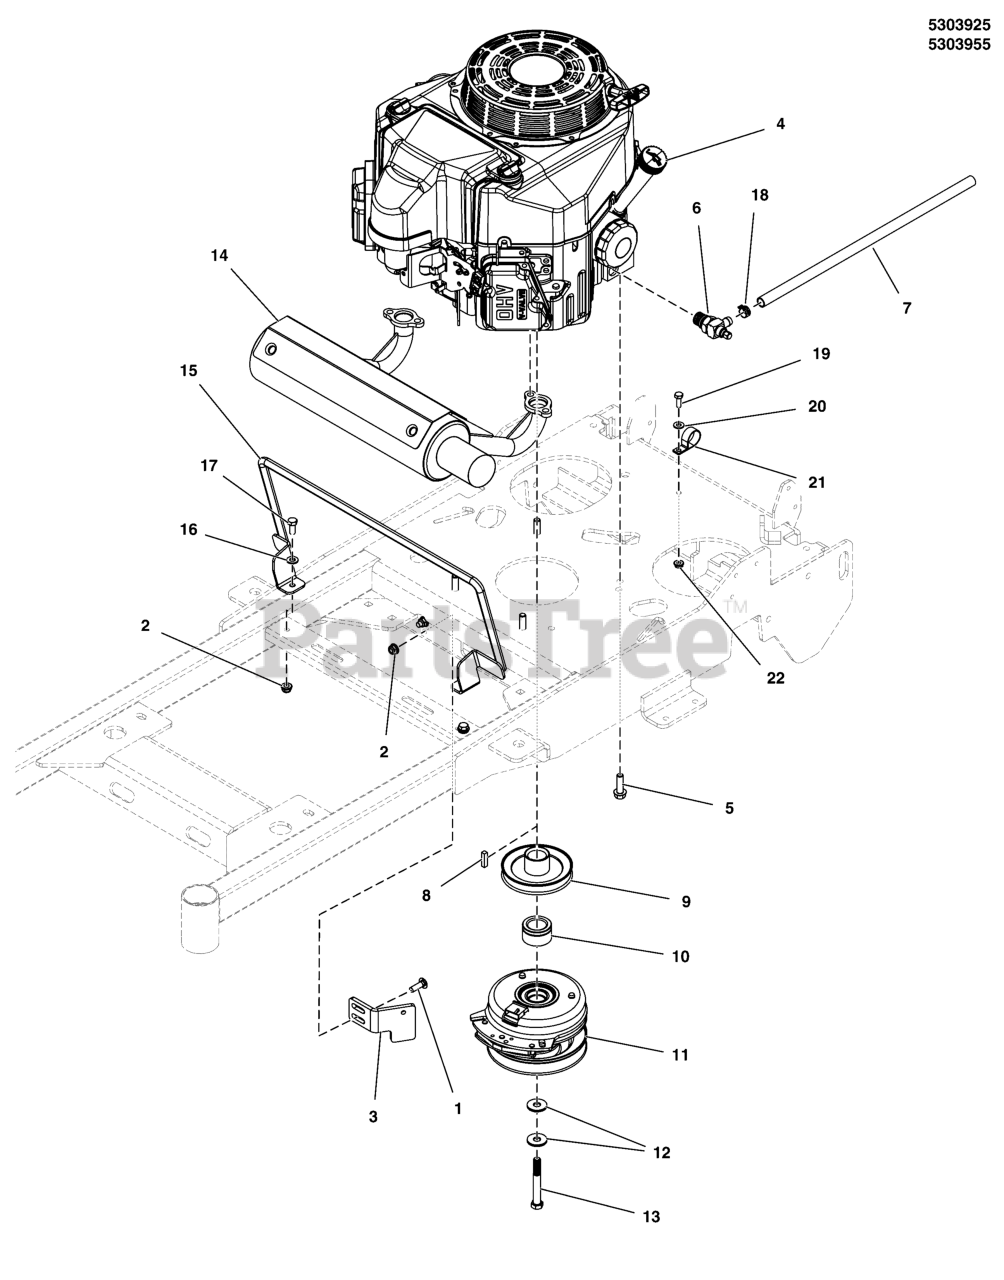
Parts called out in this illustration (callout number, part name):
1	BOLT, 5/16-18 X 1, CARRIAGE
2	NUT, 5/16-18 HEX NYLOCK FLANGE
3	PLATE, CLUTCH ANCHOR, SW25/FW25 - BLK
4	ENGINE, 18.5HP KAWASAKI, FS600V, ELEC ST
5	BOLT, 3/8-16 X 1-1/4, SF, PLT W/PATCH
6	VALVE, OIL DRAIN, 90 DEG. M20 X 2.5 THD
7	TUBING,CLEAR PVC,1/2"IDX5/8"OD X 18"LG
8	KEY, 1/4 SQ X 1
9	PULLEY, CRANKSHAFT, 1.125ID X 4.50OD, OS
10	SPACER, 1.13 X 1.75 X .75, CZ
11	CLUTCH, WARNER, 105 ft lbs - 1.13"
12	BELLEVILLE WASHER 1.1875 X .442 X .089
13	BOLT, CRANKSHAFT,7/16-20X2-3/4, GD8
14	MUFFLER, 15-19HP KAWI, WALKS
15	WELD, GUARD, MUFFLER, W25 - BLK
16	WASHER, 5/16" SAE
17	BOLT, 5/16-18 X 3/4 GD5
18	CLAMP, HOSE
19	BOLT, 1/4-20 X 3/4 GD5 CZ
20	WASHER, 1/4 SAE
21	CLAMP, VINYL INSULATED
22	NUT, 1/4-20 HEX SERR. FLANGE
